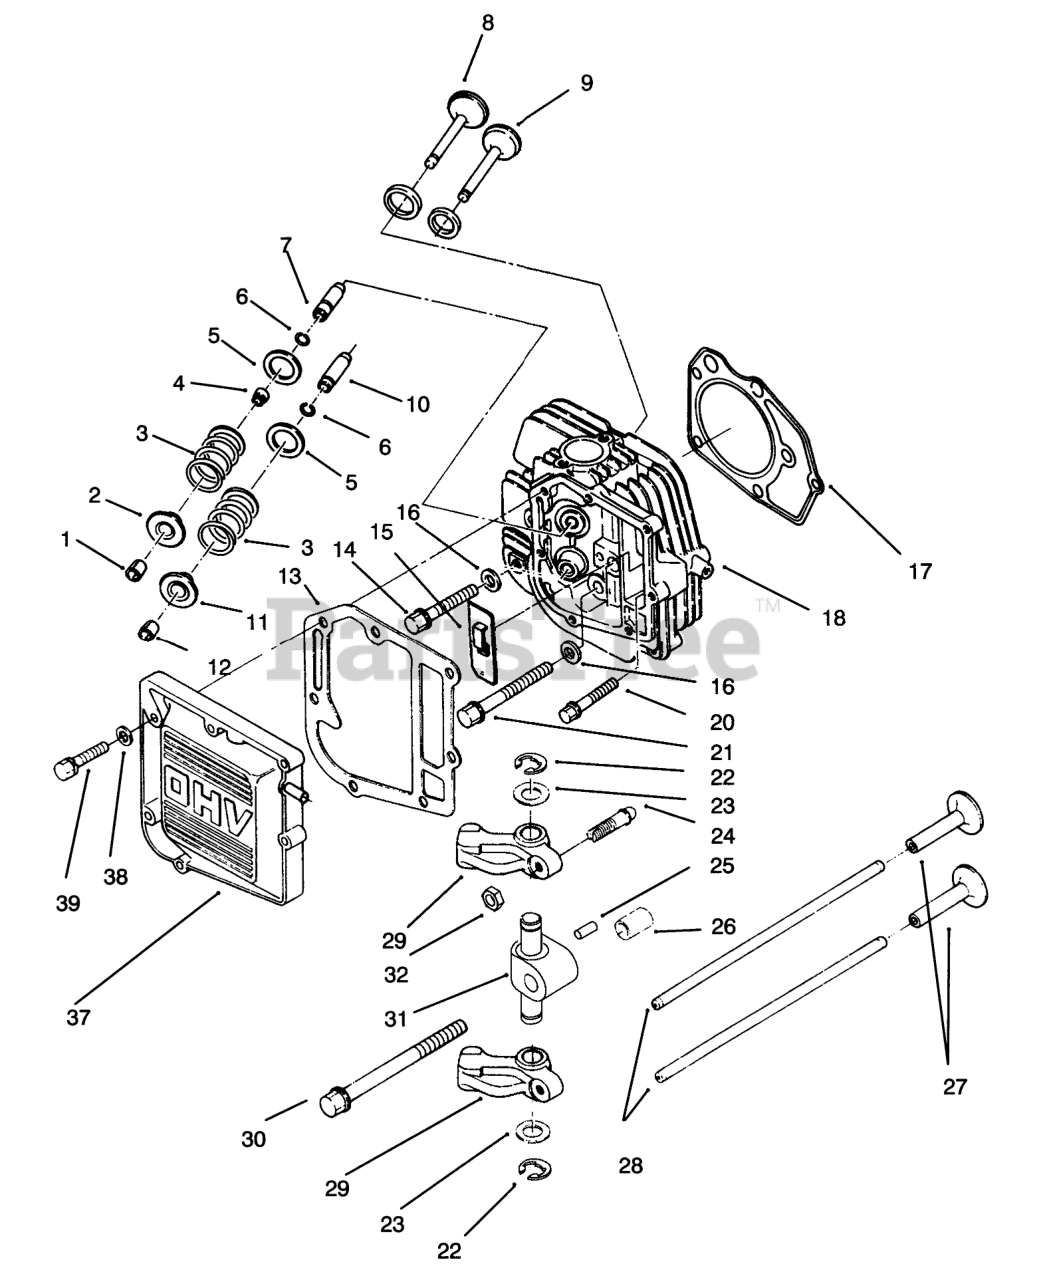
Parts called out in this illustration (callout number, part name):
1	V SPRING RETAINER LOCK
2	INT V SPRING RETAINER
3	VALVE SPRING
4	Seal-Intake
5	WASHER-VALVE SPRING
6	RING-VALVE GUIDE
7	GUIDE-INTAKE VALVE
8	VALVE-INTAKE MKD IN
9	VALVE-EXHAUST MKD EX
10	GUIDE-EXH VALVE
11	EXH V SPRING RETAINER
12	EXHAUST VALVE LOCK
13	Gasket
14	BLT-CYL HD M10X66MM
15	BREATHER
16	WASHER-FLAT M10
17	GSKT-CYL HEAD
18	Cylinder Head Assembly (Incl. Ref. #1-10, 11 & 12)
20	BLT-CYL HD M8X50MM
21	BLT-CYL HD M10X86MM
22	CLIP-RETAINER
23	ROCKER ARM WASHER
24	SCRW-LASH ADJUSTING
25	PIN-DOWEL
26	PIN-DOWEL HOLLOW
27	TAPPET
28	ROD-PUSH
29	Rocker Arm Assembly (Incl. Ref. #24 & 32)
30	BLT-CYL HD M10X125MM
31	SHAFT-ROCKER ARM
32	NUT-LASH ADJUSTING
37	VALVE COVER
38	WASHER-FLAT
39	SCRW-CP SH M6X25MM
